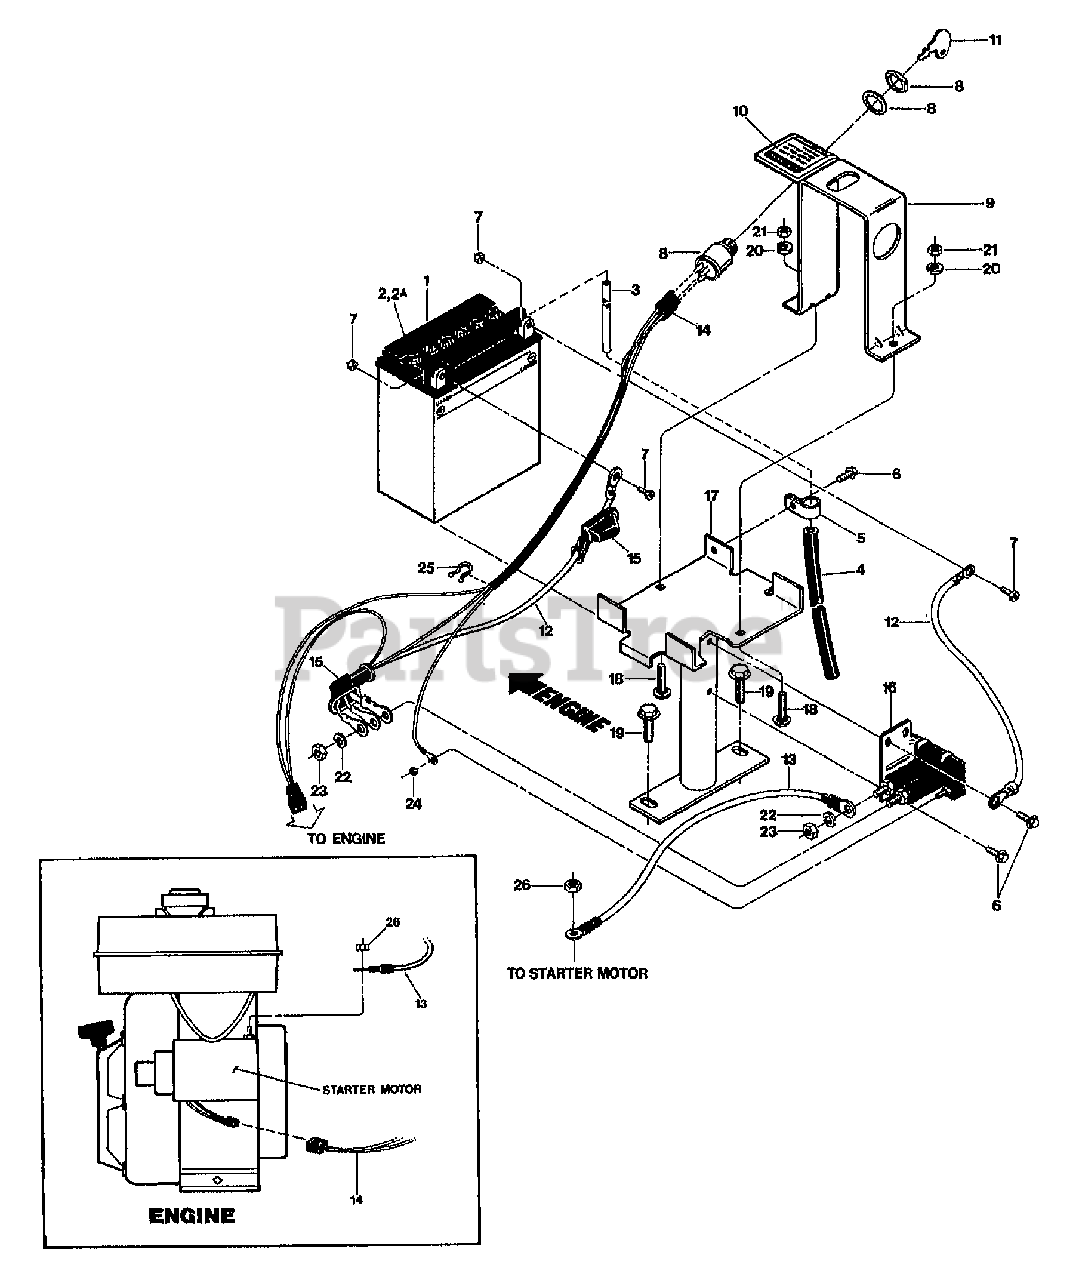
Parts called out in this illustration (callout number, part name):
1	BATTERY - 12 VOLT, 12 AMPHERE (INCL. #7)
2	CAP-YELLOW
2A	CAP-BATTERY WHITE (PONY)
3	TUBE-VENT BATTERY/HSE
4	TUBING-RUBBER (HARD PLASTIC)
5	CLAMP
6	SCR-HWH 1/4-20 X .5 STH
7	HDW PKG-BATTERY TERMINAL
8	ASSM-KEYSWITCH W/DECAL (INCL. 2 IGN. KEYS, #11)
9	KEY PLATE/CLAMP PNT (INCL. DECALS, #10)
10	DECAL-KEYSWITCH
11	KEYS(1 PAIR) FOR SWITCH
12	CABLE-BATTERY-12"
13	CABLE-BATTERY 14"
14	HARNESS-WIRE 3.5 (AVAIL. AS COMPLETE ASSY. ONLY)
15	BOOT-BATTERY CABLE
16	SOLENOID (INCL. NUTS & WASHERS FOR CABLES & WIRES)
17	BRKT-BATTERY OPC PNT
18	SCR-CARR 1/4-20X1.25
19	SCR-HFLK 5/16-18X1.00 ZP
20	WASHER-LK .25 ZP
21	NUT-HEX 1/4-20 ZP
22	WASHER-LK .312 ZP
23	NUT-HEX 5/16-24
24	NUT W/LKWASHER #10-32 ZP
25	TIE-TWIST LOCK
26	NUT-HF/LK 1/4-20 ZP
